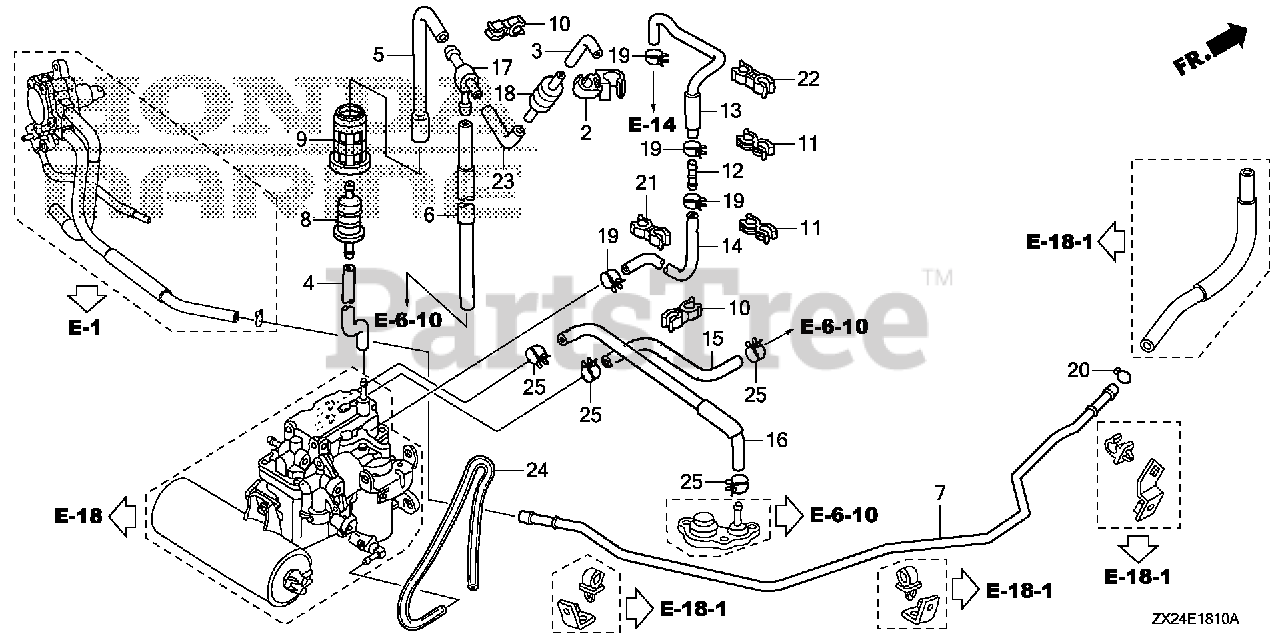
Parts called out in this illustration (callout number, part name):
2	CLAMP, CHECK VALVE
3	TUBE, CHECK VALVE
4	TUBE A, AIR VENT
5	TUBE B, AIR VENT
6	TUBE, AIR VENT
7	PIPE, FUEL
8	FILTER, FUEL PUMP
9	SUSPENSION, STRAINER
10	CLAMP, HOSE
11	CLIP, TUBE
12	JOINT, FUEL RETURN
13	HOSE A, PRESSURE REGULATOR RETURN
14	HOSE B, PRESSURE REGULATOR RETURN
15	TUBE, WATER INLET
16	TUBE, WATER OUTLET
18	VALVE, CHECK
19	CLAMP, TUBE (D10.7)
20	CLIP, TUBE (B12)
21	CLIP, WIRE
22	CLAMP, FUEL TUBE
23	BULK HOSE, FUEL (3.5X3000) (3.5X55)
24	BULK HOSE, VINYL (3.5X6.5X8000) (3.5X6.5X600)
25	CLAMP, TUBE (D10.5)
